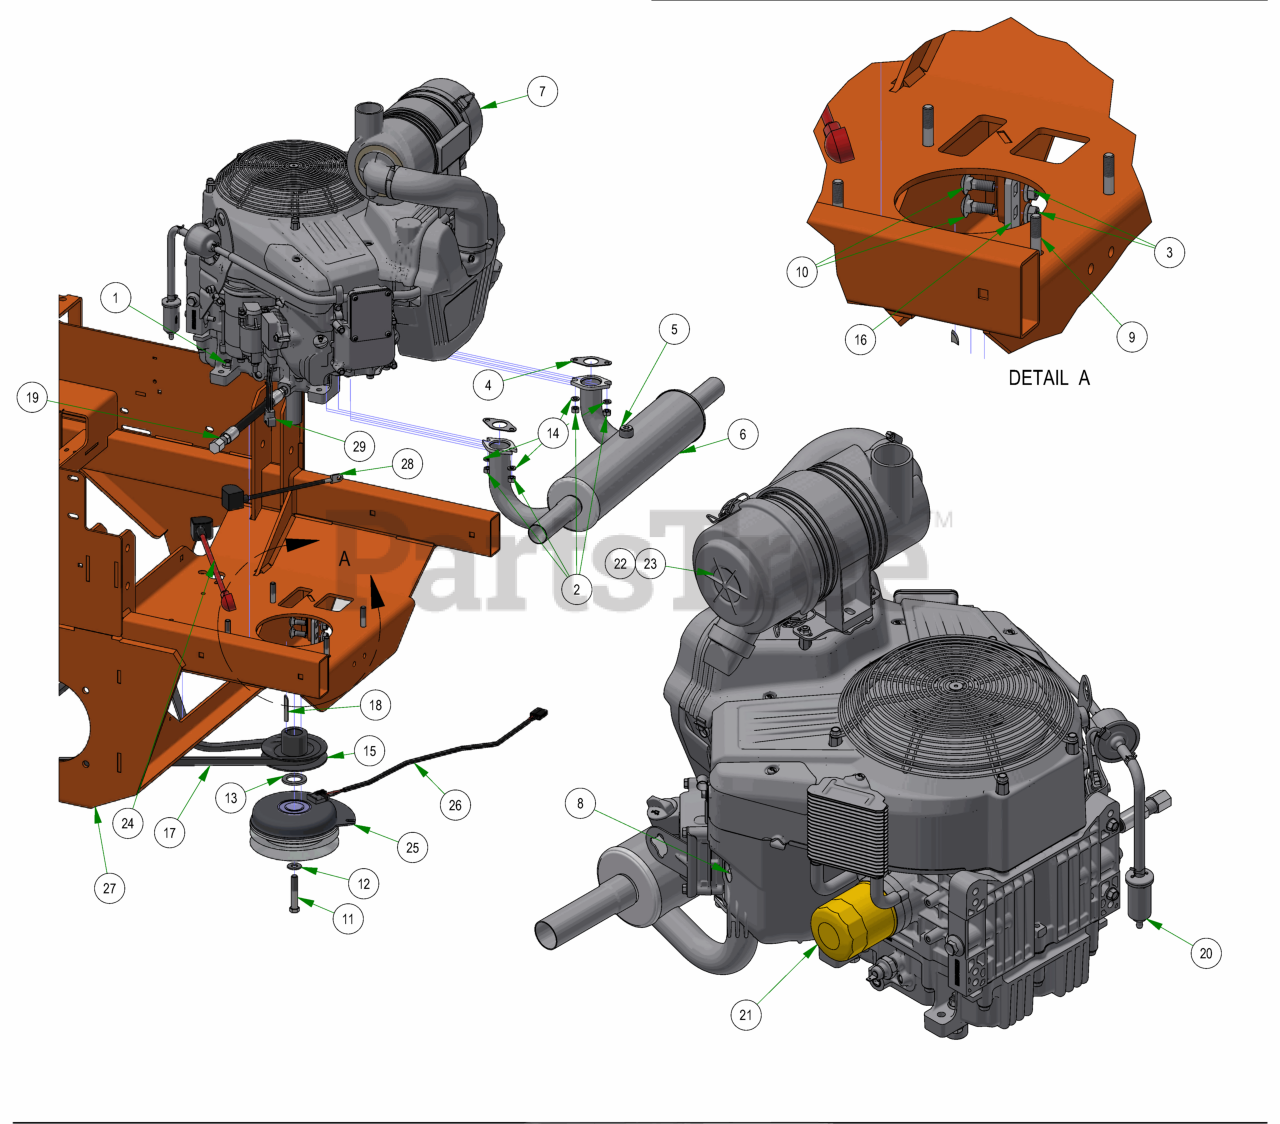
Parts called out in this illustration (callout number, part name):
1	3/8-16 HEX FLANGE TOP LOCKNUT ZINC
2	M8-1.25 DIN 934 HEX NUT (CL.8) ZINC
3	3/8-16 NYLON INSERT FLANGE LOCKNUT (GR.F) ZINC
4	Exhaust Gasket for 23 Vanguard
5	O2 Sensor Plug
6	Muffler for 36Hp Vanguard
7	VANGUARD 37EFI VERTICAL SHAFT ELECTRIC THROTTLE
8	Spark Plug
9	3/8-16x1-3/4 Gr5 Hex Flange Screw Zinc Clear
10	3/8-16 X 1 CARRIAGE BOLT (GR.5) ZINC
11	7/16-20 X 2-1/2 HEX Bolt GR 8 W/ Patch
12	3/8 FLAT WASHER USS (1" OD) ZINC
13	1.140 ID X 1.750 OD X .132 THICK FLAT WASHER PLAIN
14	5/16 SPLIT LOCKWASHER ZINC
15	4 3/4 Motor Pulley
16	Rebel Clutch Tab
17	2019 Rebel Pump Belt
18	1/4 X 2 SQ MACHINERY KEY 1018 STL PLAIN
19	14 mm Oil drain Hose 993cc Vanguard
20	Universal Inline Fuel Filter
21	Oil Filter
22	Canister Air Filter- Outer
23	Canister Air Filter- Inner
24	14" Red Battery Cable
26	Clutch Pigtail
27	2023 Rebel Frame - Painted
28	Starter Cable
29	2024 Vanguard EFI Vertical Engine Pigtail for Electric Throttle
